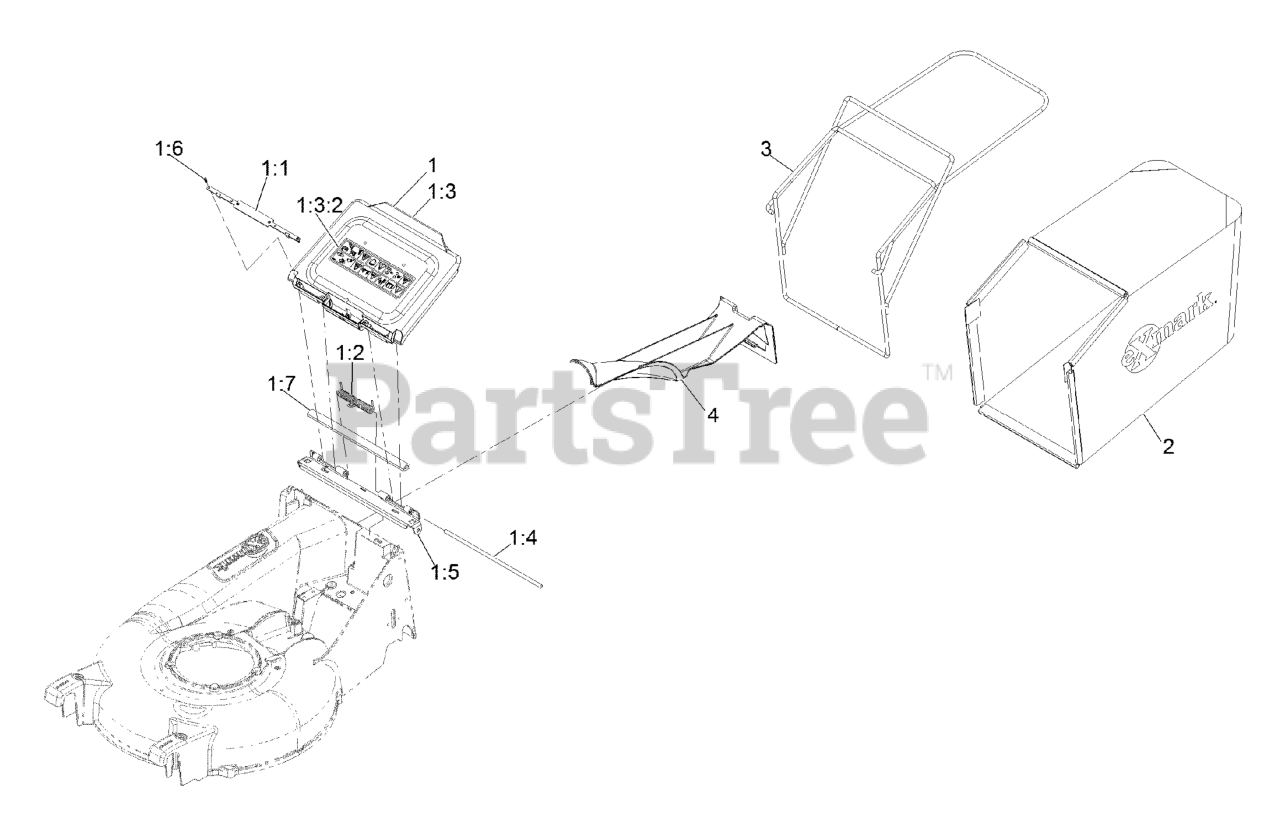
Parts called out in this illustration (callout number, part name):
1	DOOR ASM
1:1	PLATE, DOOR COVER
1:2	SPRING-PLASTIC DOOR
1:3	ASM-DOOR & DECAL
1:3:2	DECAL-WARNING
1:4	PIN-DOOR PIVOT
1:5	BRACKET-DOOR PIVOT
1:6	SCR,TAP,6-19X7/16,PHPH, S
1:7	SEAL-EPDM FOAM BULB
2	BAG-21 GRASS
3	WLD-BAG FRAME
4	PLUG,MULCH
